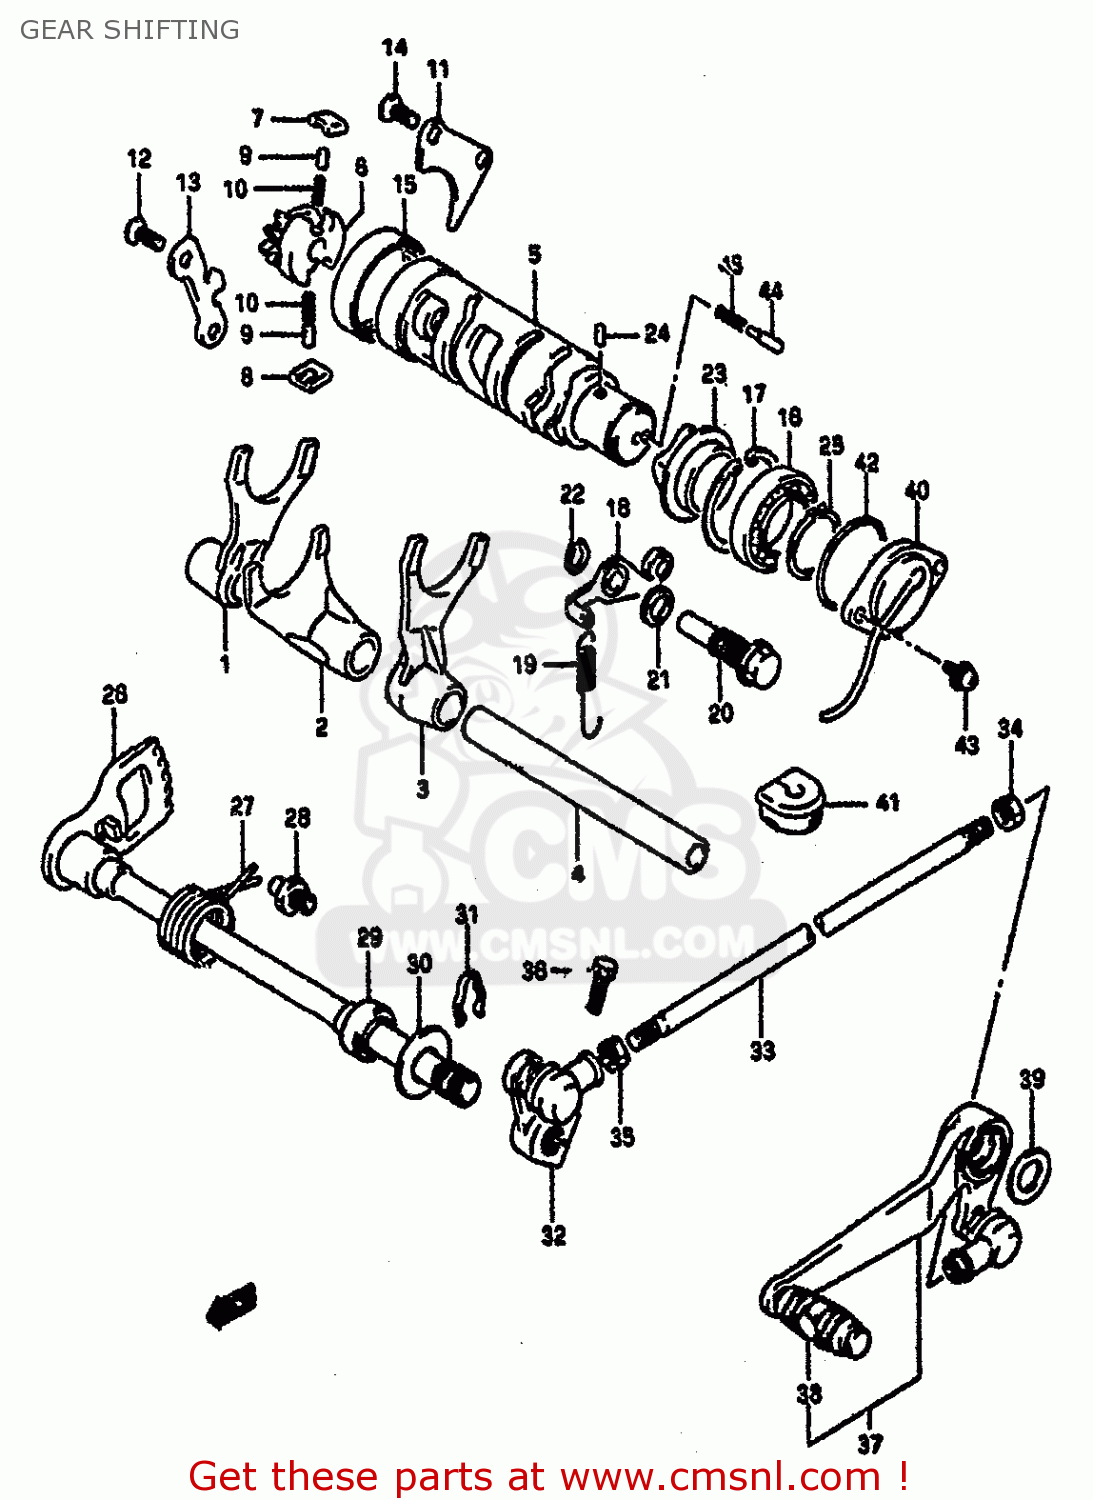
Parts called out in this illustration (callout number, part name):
1	FORK,GEAR SHIFT NO.1
2	FORK,GEAR SHIFT NO.2
3	FORK,GEAR SHIFT NO.3
4	SHAFT,GEAR SHIFT FORK(L:128)
5	CAM,GEAR SHIFT
6	GEAR,GEARSHIFT CAM DRIVE
7	PAWL,GEAR SHIFT NO.1
8	PAWL,GEAR SHIFT NO.2
9	PIN(5X8)
10	SPRING
11	LIFTER,GEAR SHIFT PAWL
12	SCREW
13	GUIDE,GEAR SHIFT CAM
14	SCREW
15	BEARING(43X49X12)
16	BALL BEARING
17	CIRCLIP
18	STOPPER,GEAR SHIFT CAM
19	SPRING
20	SHAFT,GEAR SHIFT CAM STOPPER
21	GASKET(10X14X3.6) (NAS)
22	CIRCLIP
23	PLATE,STOPPER
24	PIN 4X6
25	CIRCLIP
26	SHAFT,GEAR SHIFT
27	SPRING
28	STOPPER,GEAR SHIFT CAM
29	OIL SEAL
30	WASHER (12.5X27X1.6)
31	SPRING,RETAINER
32	ARM,GEAR SHIFT LINK
33	ROD,GEAR SHIFT LINK
34	NUT
35	NUT 6MM
36	BOLT
37	LEVER ASSEMBLY,GEAR SHIFTING
38	RUBBER,GEAR SHIFT PEDAL
39	WASHER(18X24X1)
40	TERMINAL BASE ASSY,NEUTRAL
41	GROMMET,LEADWIRE
42	O RING(D:2.4,ID:36.5)
43	SCREW
44	PIN(5X15.5)
45	SPRING
